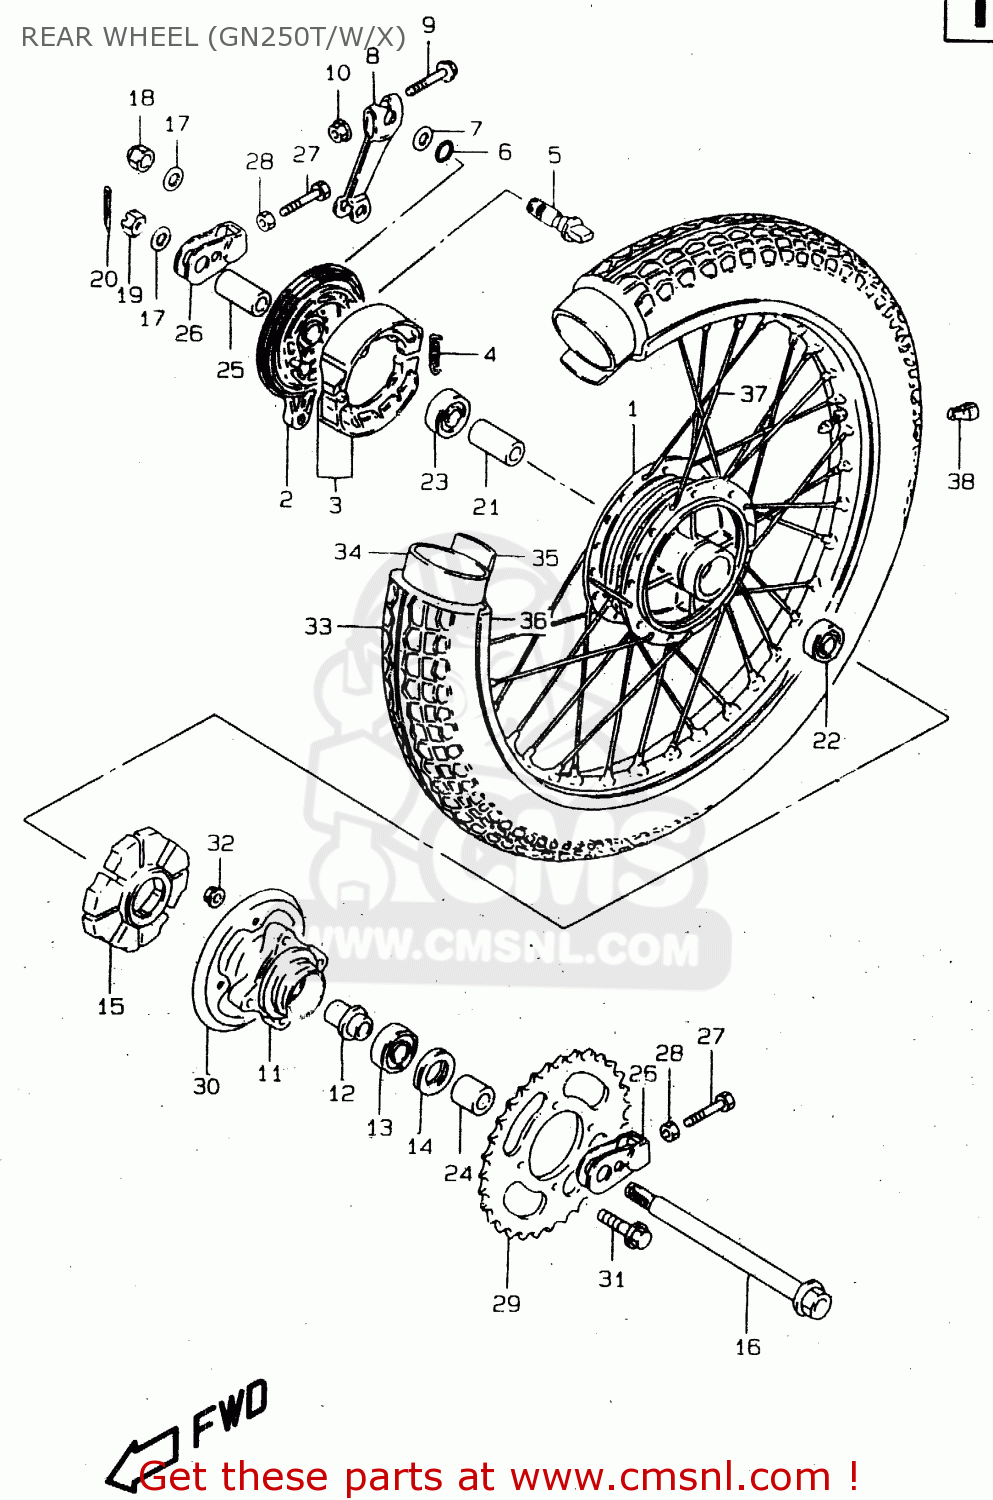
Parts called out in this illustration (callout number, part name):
1	HUB,RR WHEEL
2	PANEL,RR BRAKE ANCHOR
3	SHOE SET,BRAKE (NAS)
4	SPRING(L:34)
5	CAM,BRAKE
6	O RING(D:2.5,ID:13.8)
7	WASHER(14.5X22X1.6)
8	LEVER,RR BRAKE CAM
9	BOLT
10	NUT
11	DRUM,RR SPROCKET MOUNTING
12	RETAINER,RR SPROCKET DRUM
13	BEARING(20X47X14)
14	SEAL,OIL(28X47X7)
15	ABSORBER ASSY,HUB SHOCK
16	AXLE,REAR
17	WASHER
18	NUT
19	NUT
20	COTTER PIN
21	SPACER(15.3X21.7X63)
22	BEARING
23	BEARING
24	SPACER(15X28X24.8)
25	SPACER(15X22X46.8)
26	ADJUSTER,CHAIN
27	BOLT(8X50)
28	NUT
29	SPROCKET,RR(NT:41-520)
30	GUIDE,RR SPROCKET CHAIN
31	BOLT(10X40)
32	NUT
33	TIRE,RR
34	TUBE ASSY,WHEEL,INNER 4.60-16
35	PROTECTOR,WHL INR TUBE
36	RIM,RR WHEEL(215X16)
37	SPOKE ASSY,RR WHEEL
38	BALANCER,WHEEL (B)
